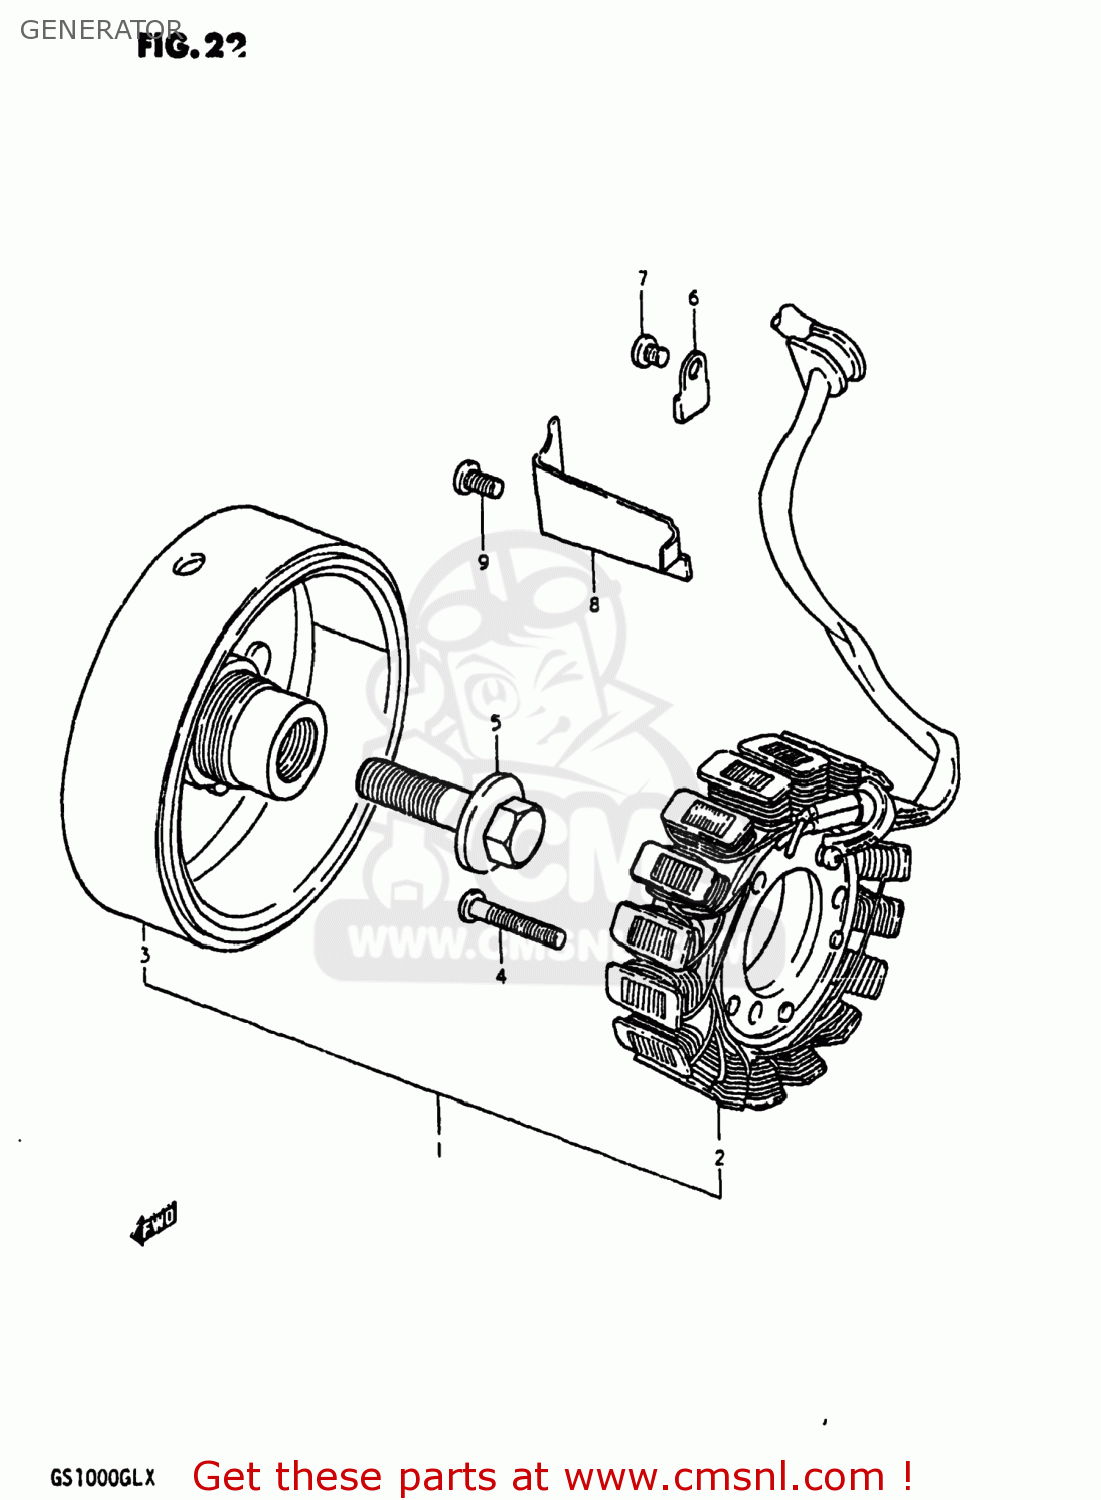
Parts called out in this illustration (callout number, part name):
1	GENERATOR ASSEMBLY
2	STATOR ASSEMBLY
3	ROTOR
4	SCREW 6X30
5	BOLT 12X45
6	CLAMP,GENERATOR LEAD WIRE
7	SCREW
8	CLAMP,GENERATOR LEAD WIRE
9	SCREW
